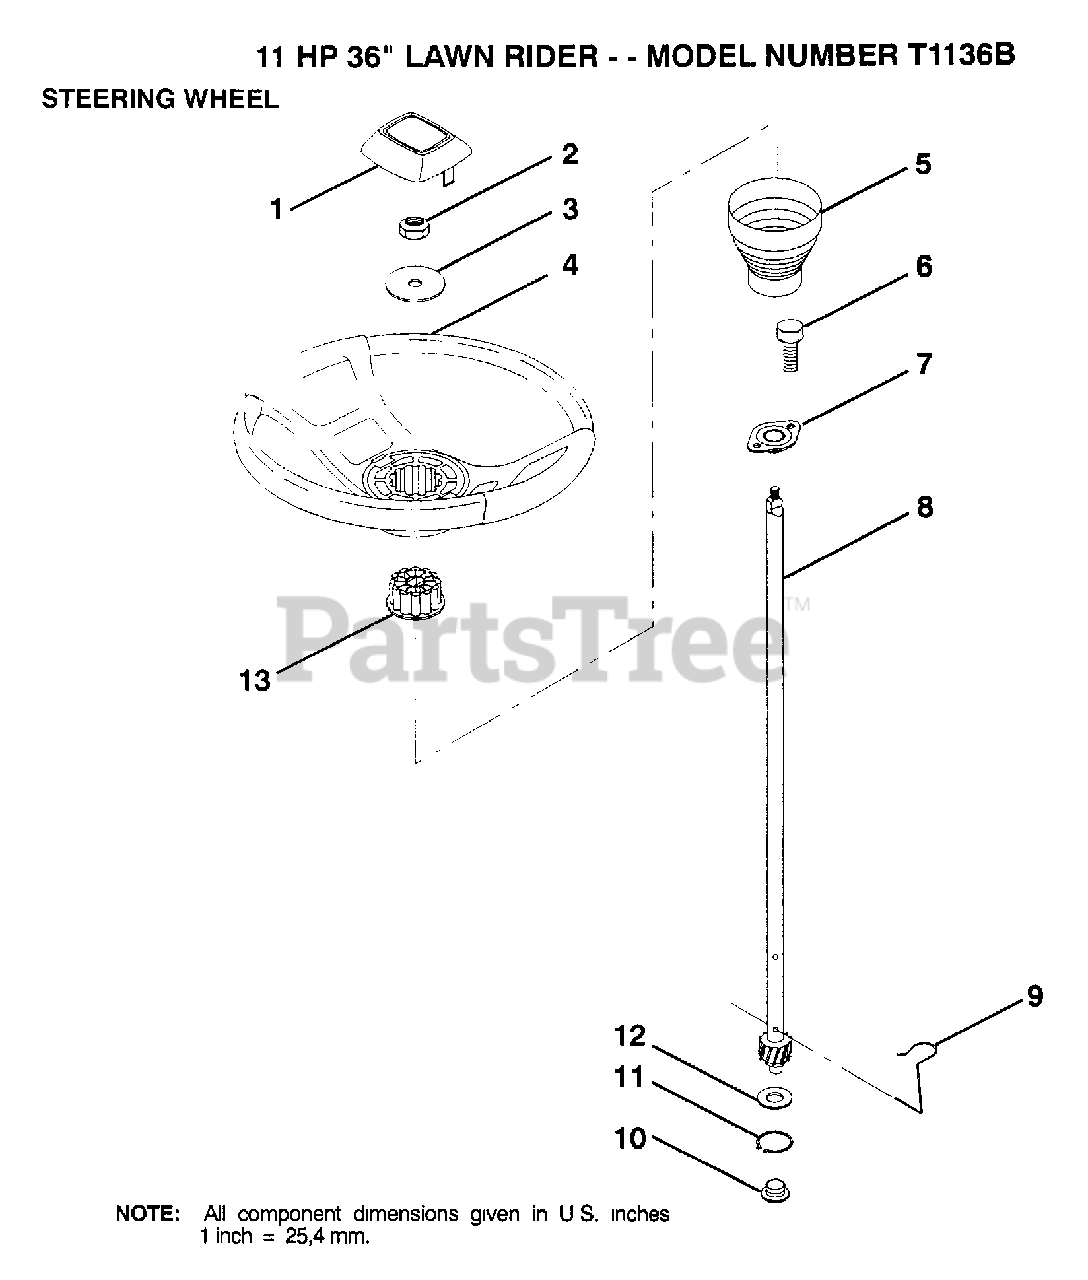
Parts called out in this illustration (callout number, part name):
1	ST WHL INSERT CAP
2	GRIPCO NUT
3	WASHER T
5	SLEEVE STEERING
9	STEERING CLIP
10	BUSHING STEER LWR
11	RING
12	WASHER LT
13	ADAPTER-WHEEL LT
